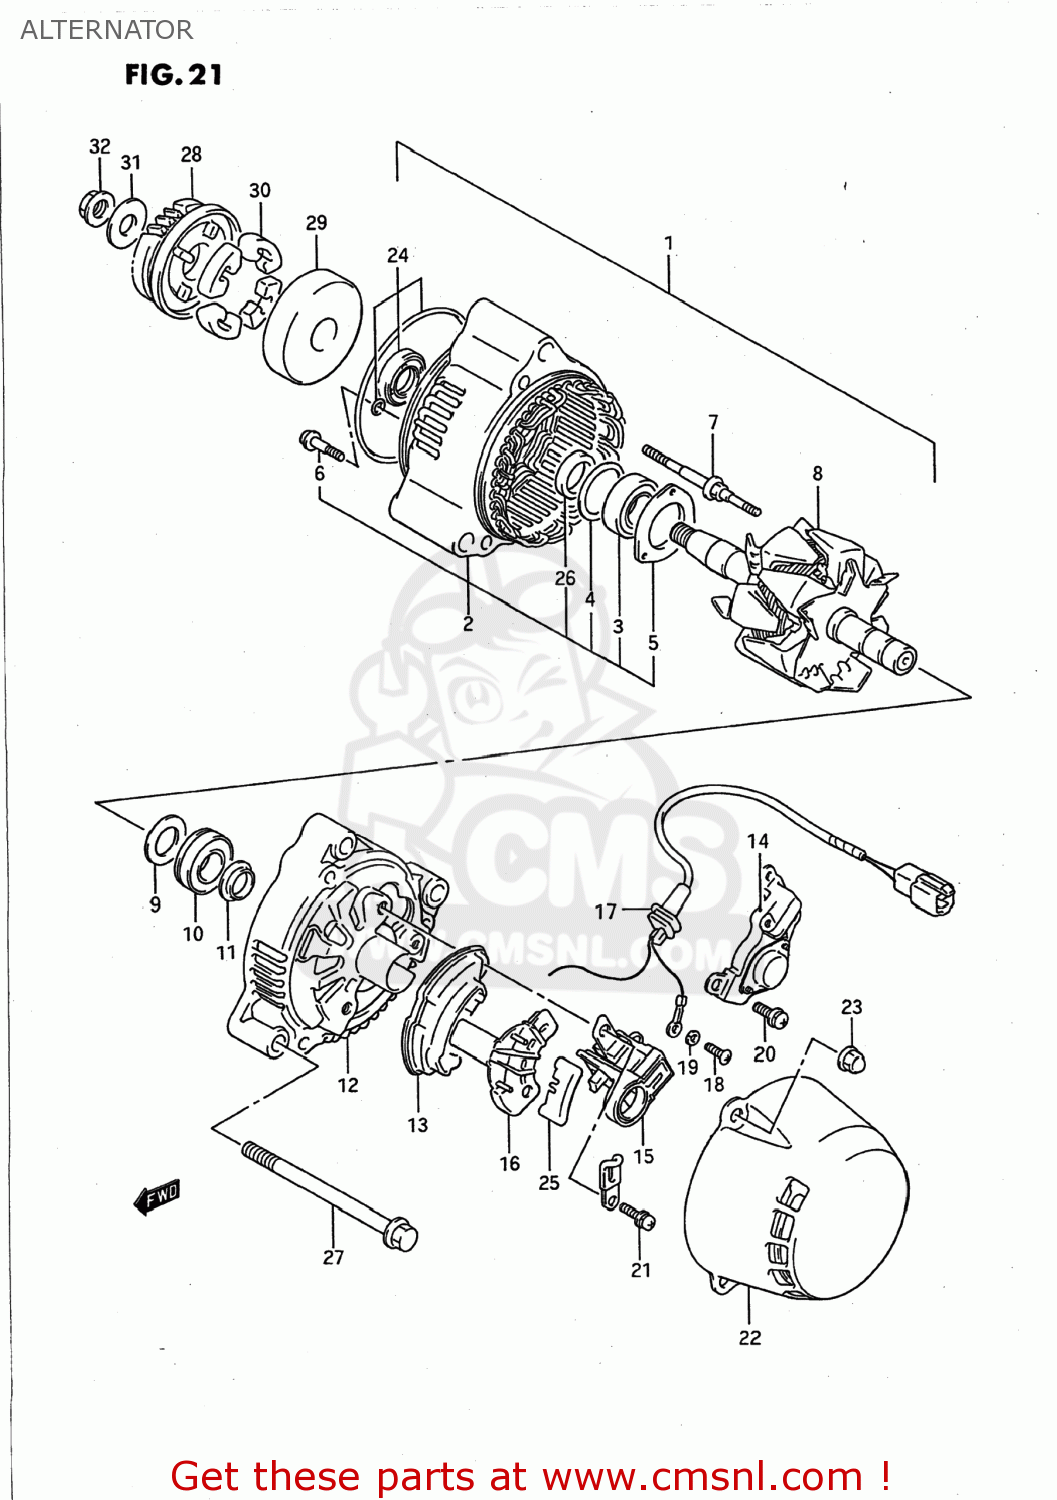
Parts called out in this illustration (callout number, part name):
1	ALTERNATOR ASSEMBLY
2	FRAME,DRIVE END
3	BEARING
4	COVER,BEARING
5	RETAINER
6	SCREW,BEARING RETAINER
7	STUD BOLT
8	ROTOR ASSEMBLY
9	COVER,BEARING
10	BEARING
11	COVER(2)
12	FRAME,END
13	HOLDER,RECTIFIER
14	REGULATOR
15	HOLDER,BRUSH
16	COVER,RECTIFIER
17	WIRE,LEAD
18	SCREW
19	WASHER,LOCK
20	SCREW
21	SCREW
22	COVER
23	NUT
24	SEAL SET,OIL
25	BUSH
26	SPACER
27	BOLT
28	GEAR,GENERATOR DRIVEN
29	HOUSING,GENERATOR GEAR
30	DAMPER,GENERATOR DRIVEN
31	WASHER
32	NUT
